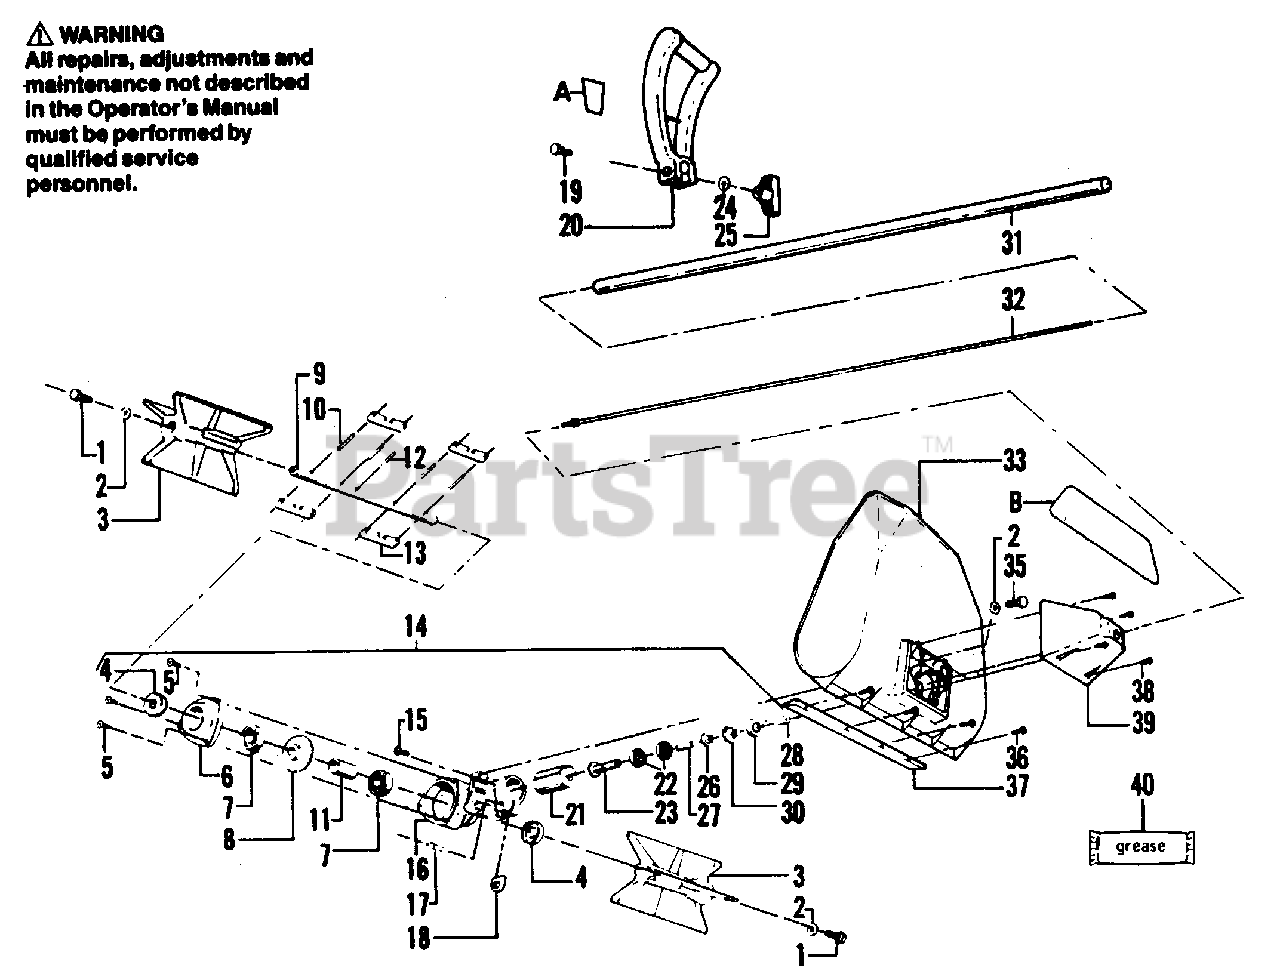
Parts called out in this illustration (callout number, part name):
1	Screw - Impeller - #1/4 - 20 x 1/2" - Hex Cap
2	Washer - #1/4 - Impeller & Gear Box Mtg.
3	Impeller
4	Oil Seal - Double Lip
5	Screw - Gear Housing
6	Gear Housing Cover
7	Bearing - Shaft
8	Gear - Spiral Bevel
9	Output Shaft
10	Pin - Spiral - Brace
11	Collar - Shaft
12	Pin Spiral - Gear
13	Brace - Impeller
14	Gear Box Ass'y (Inc.4-8, 11, 15-18 & 21-30)
15	Screw - Index #10 - 24 x 7/16" Pan Hd.
16	Gear Housing
17	Screw - Pinch Clamp - #1/4 - 20 x 3/4" - Hex Socket Head
18	Washer - Fiber Filler
19	Screw - #1/4 - 20 x 1-3/4" Assist Handle
20	Assist Handle
21	Sleeve - Housing
22	Bearing - Pinion
23	Pinion Gear - Spiral Bevel
24	Washer - #1/4 - Assist Handle
25	Knob - Assist Handle
26	Retaining Ring - Pinion
27	Collar Pinion
28	Plug - Grease
29	Oil Seal - Single Lip
30	Retaining Ring - Bearing
31	Drive Shaft Housing Ass'y. (Inc.32)
32	Drive Shaft
33	Housing - Impeller
35	Screw - #1/4 - 20 x 3/4" - Gear Box Mounting
36	Screw - Scraper Bar - #8 - 12 x 3/4" - Fil. Hd.
37	Scraper Bar
38	Screw - Rear Cover - #8 - 12 x 3/4" - Fil. Hd.
39	Cover - Rear
40	Grease (Optional)
A	Decal - Assist Handle
B	Decal - Caution and Model
